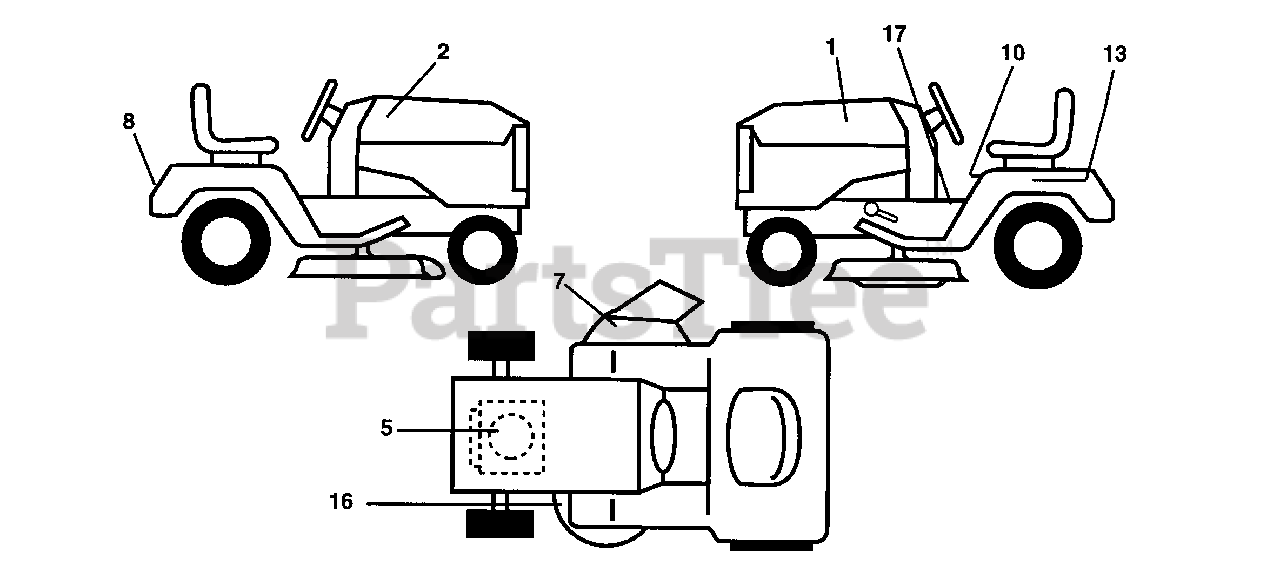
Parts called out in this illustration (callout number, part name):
1	Decal, Hood, L. H.
2	Decal, Hood, R. H.
5	Decal, Engine
7	Decal, Warning Multi/Lang
8	Decal,Logo, Fender
10	Decal Caution Fender
13	Decal, Caution, Battery
16	Decal, V-Belt Sch.
17	Decal, inst. Oper.
